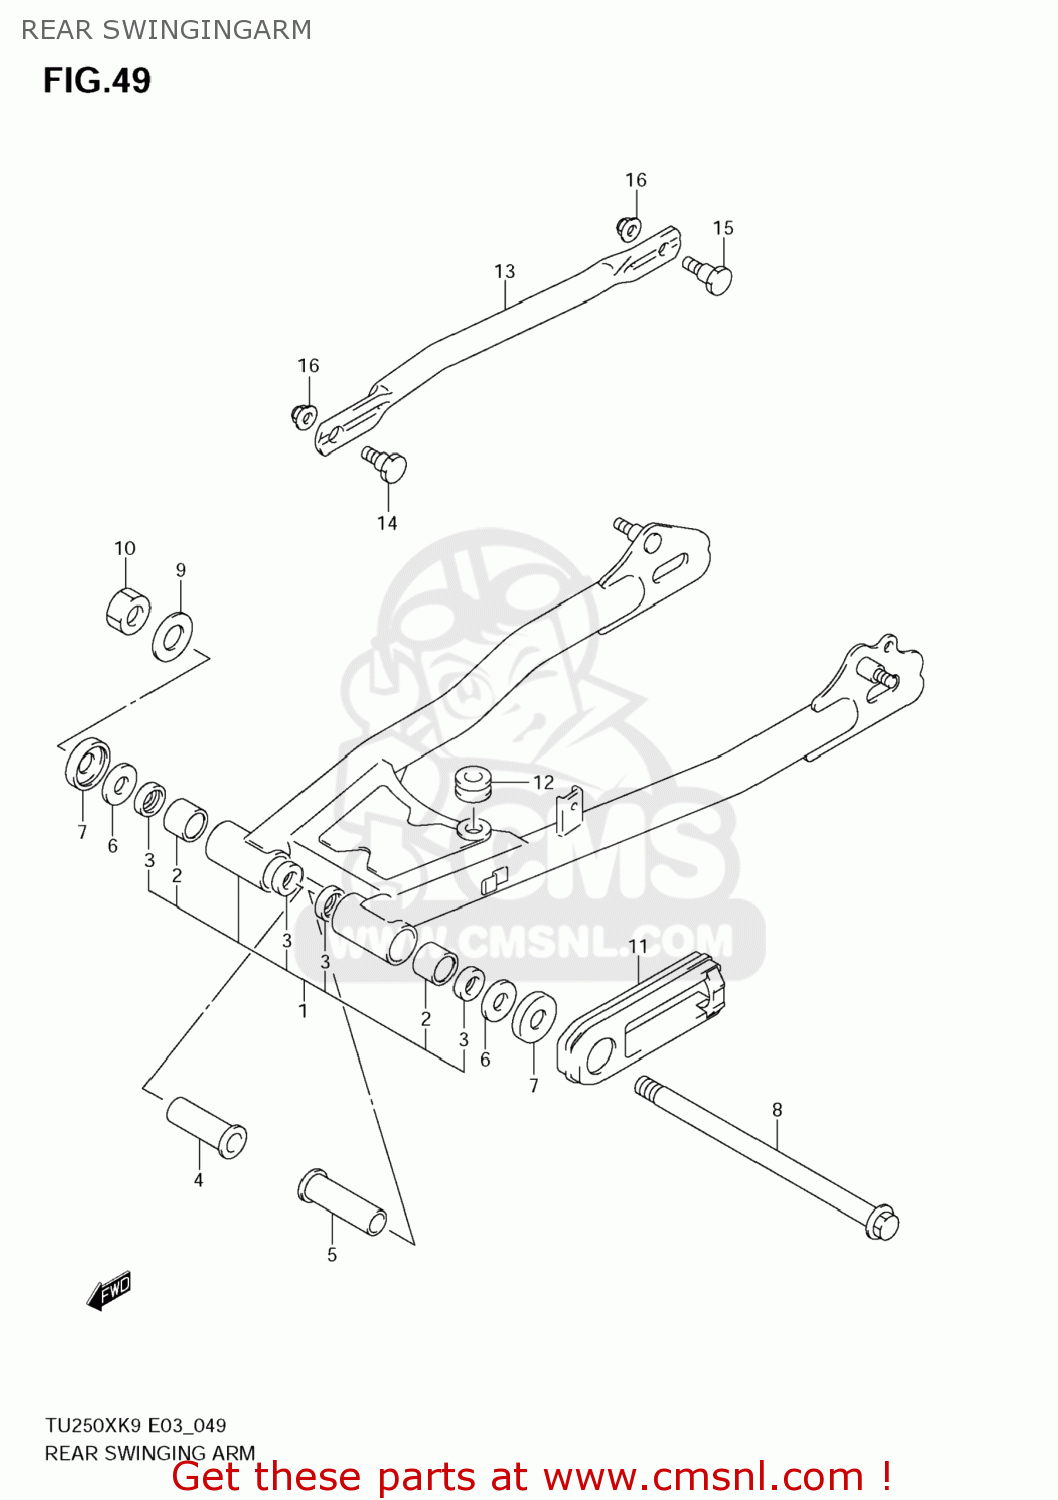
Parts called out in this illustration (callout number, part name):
1	SWINGINGARM ASSY,RR
2	BUSHING,RR SWGARM PIVOT
3	SEAL,OIL(20X27X5)
4	SPACER,RR SWGARM PIVOT,R
5	SPACER,RR SWGARM PIVOT,L
6	WASHER
7	COVER,RR SWINGINGARM PIVOT
8	SHAFT,RR SWINGINGARM PIVOT
9	WASHER
10	NUT
11	BUFFER,CHAIN TOUCH DEFENSE
12	CUSHION
13	TORQUELINK,RR
14	BOLT(8X21)
15	BOLT(8X24)
16	NUT
